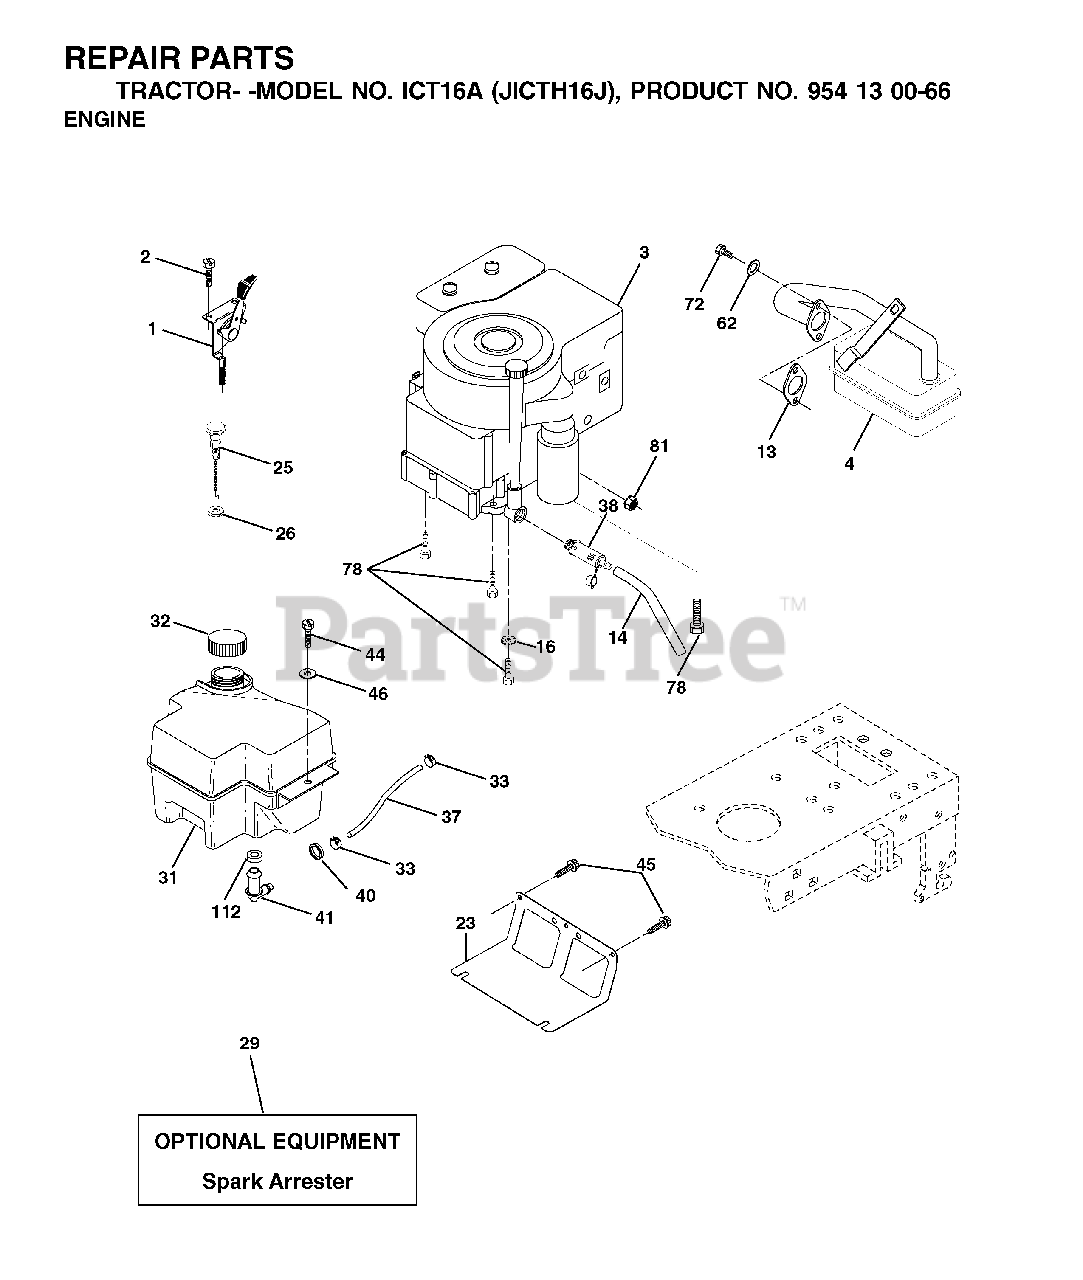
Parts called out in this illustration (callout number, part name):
1	CONTROL TH/CH FLAG
2	SCREW
13	REPL BY 532 27 22-93
14	TUBE, DRAIN OIL ASM.
16	LOCKWASHER
23	SHEILD.BROWNING.DBR.GUARD
26	NUT KEPS 3/8 - 24 UNF
29	ARRESTER SPARK (OPTIONAL)
31	GAS TANK 2GAL
32	FUEL CAP
33	HOSE CLAMP
37	LINE.FUEL.20
38	PLUG, OIL DRAIN EASY
40	GROMMET T
41	STEM FUEL TANK
44	SCREW HEXWSHR 1/4-20X3/4
45	SCREW, 3/8-16X3/4
62	LOCKWASHER
72	SCREW
78	SCREW.3/8-16
81	NUT
112	BUSHING OUTLET T
